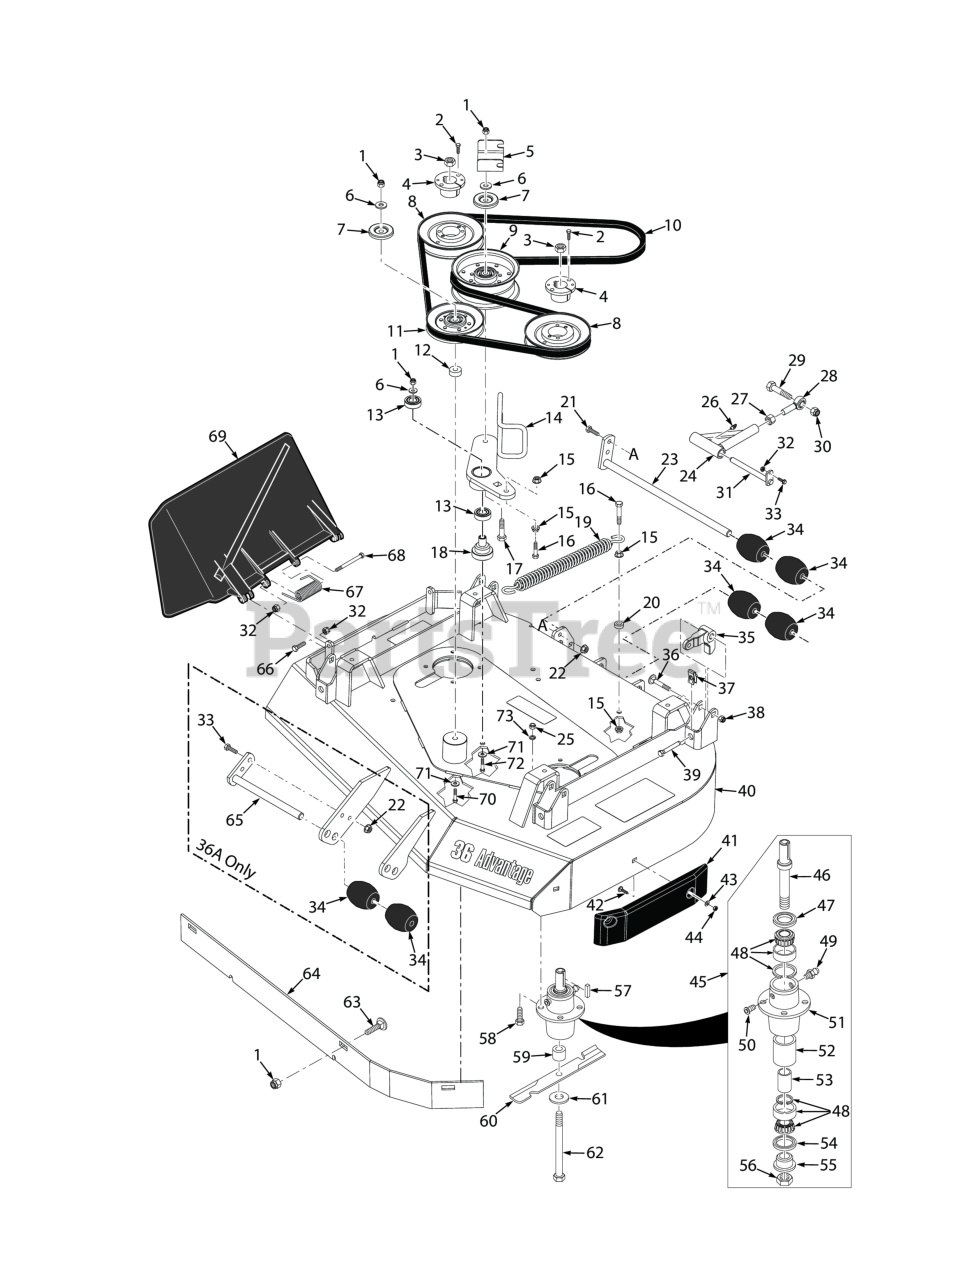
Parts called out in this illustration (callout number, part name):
1	HEX NUT, ELASTIC STOP LOCK, 3/8-16
2	Bolt, Hex Head 1/4-20 x 1" Grade 8 Black
3	Hex Locknut, Elastic Stop, 3/8-16
4	Hub, Tapered 1-1/8" Bore
5	Bracket, Belt Guide
6	Flatwasher, 3/8 (.391 x .938 x .105 HD) Grade 8
7	Quick Pin, 5/16" Dia.
8	Pulley, 5.13" Dia. - 48V
9	Pulley, Idler 5" Dia.
10	Belt, Cutter Deck
11	IDLER PULLEY, "V" GROOVE
12	SPACER, J PULL ROD
13	BEARINGS, BALL, NEUTRAL RETURN
14	Idler Arm Assembly
15	NUT, 3/8-16 SERRATED FLANGE HEX HEAD
16	Bolt, Hex Head 3/8-16 x 1-1/2" Grade 8 Black
17	Capscrew, Hex Head 3/8-16 x 3.25"
18	Pivot, Idler
19	Spring, Cutter Deck
20	SPACER, IDLER
21	Bolt, Carriage 5/16-18x1" (large frame units only)
22	Nut, Flange Head Elastic Stop 5/16-18
23	Shaft Weldment
24	Pusharm Assembly, LH
25	Lock Nut, 5/16-18 Elastic Stop Grade 8
26	Grease Fitting, 90 Degree
27	Nut, Hex Head 5/8-18 UNF
28	Rod End, 5/8" Male RH Thread
29	BOLT, HEX HEAD 5/8-11 X 4-1/2"
30	HEX LOCKNUT, ELASTIC STOP, 5/8-11
31	Shaft Weldment, Pusharm Mounting
32	HEX NUT, ELASTIC STOP LOCK, 5/16-18
33	Bolt, Heax Head 5/16-18 x 1" (48V / 52V)
34	Wheel, Anti-Scalp
35	Lever, Deck Level
36	Bolt, Carriage 7/16-14 x 2-1/4"
37	U-Nut, 3/8-16 (short)
38	HEX LOCKNUT, ELASTIC STOP, 7/16-14
39	Bolt, Hex Head 3/8-16 x 2-1/2" Soecial Lock
40	Cutter Deck w/Decals (32)
41	Pad, Deck Wear
42	Bolt, 5/16-18 x .75 RHSN Carriage
43	Flatwasher, 5/16-.344 x .688 x .065 (48V / 52V)
44	Nut, Center Lock, 5/16-18(32)
45	Cutter Spindle Assembly
46	Spindle Shaft, Tapered Brng
47	SEAL, 2.00 O.D. X 1.50 BORE
48	Tapered Bearing Set (Two Bearings W/Race)
49	GREASE FITTING, STR. 1/4-28 SELF TAP.
50	RELIEF FITTING, TAPERED BEARING SPINDLE
51	Housing, Spindle
52	Spacer, Outside, Cutter Spindle
53	SLEEVE, CUTTER SPINDLE
54	Seal, 2.00" O.D. x 1.625" Bore
55	SPINDLE BUSHING, BOTTOM
56	Nut , Spec ial 1 -1/ 1 6 - 1 8
57	Key, 1/4 x 1/4 x 2.0"
58	Bolt, Hex Head 5/16-18 x 1-3/4" Grade 8
59	Spacer, Spindle Bottom
60	Cutter Blade, 16-1/2" (48V)
61	Flatwasher, 5/8-.688 x 1-3/4 x .134 HD
62	BOLT, HEX HEAD, 5/8-11 X 9-1/2 GR.5
63	Carriage Bolt, 3/8-16 x 1.0"
64	Baffle, Flange (32)
65	Shaft Weldment, Guide Roller
66	Bolt, Hex Head 5/16-18 x 1-1/2" - Front
67	Spring, Discharge Chute
68	Bolt, 5/16-18 x 4-3/4" Hex Head
69	Discharge Chute Advantage - Small
70	Bolt, Hex Head 3/8-16 x 4-3/4"
71	Flatwasher, 3/8-.406 x 1-1-1/2 x 7 Gauge
72	Capscrew, Hex Head 3/8-16 x 3.25"
73	Lockwasher, 5/16 (.317 x .586 x .078) Helical Spring
